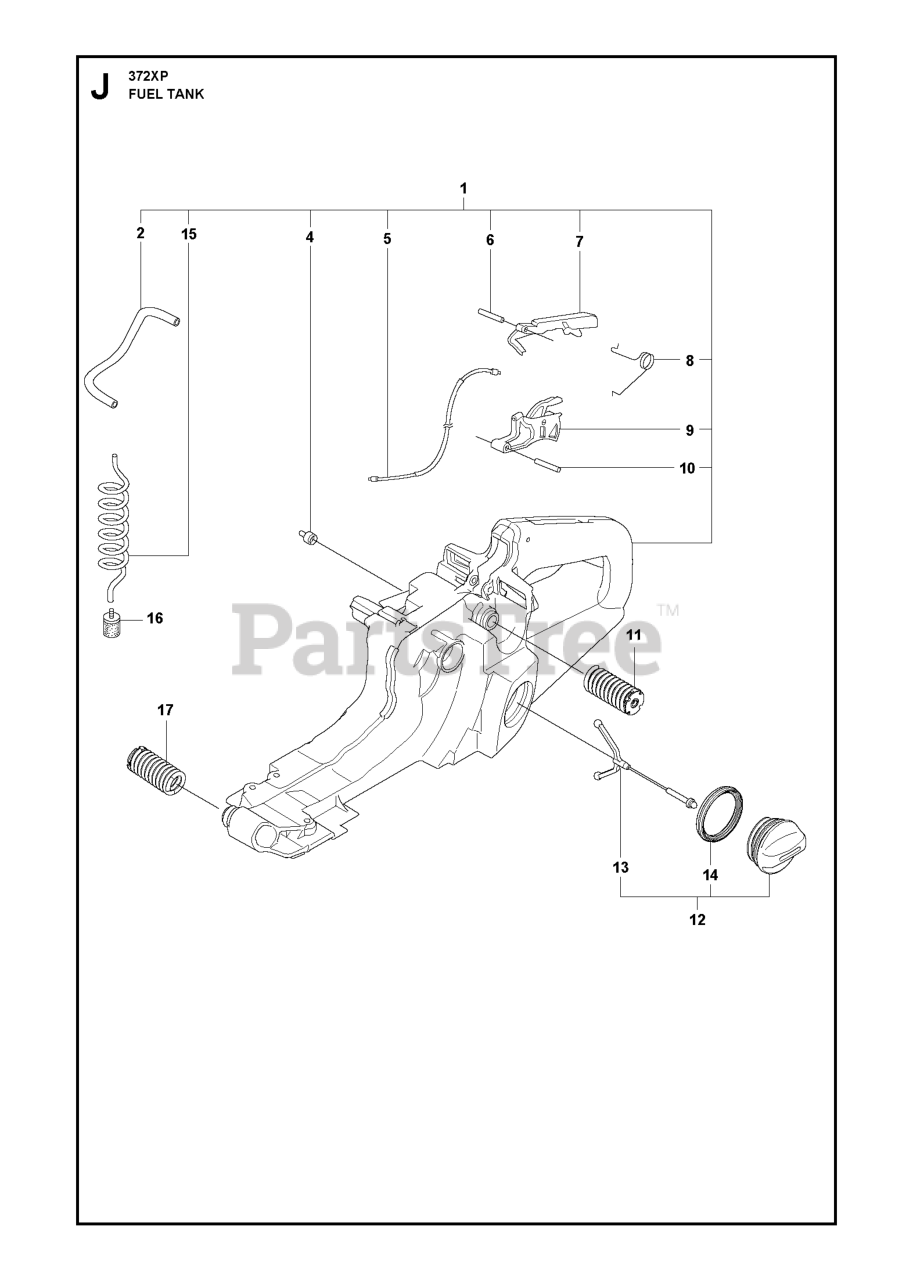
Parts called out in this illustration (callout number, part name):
2	FUEL HOSE STRAIGHT 105
3	CONNECTOR
4	FILTER PLUG
4	TANK VALVE
4	FUEL TANK VENT
6	PIN 3X25
7	THROTTLE CATCH
9	THROTTLE TRIGGER
10	PIN CPH8 4X20
11	ANTIVIBE MOUNT
15	FUEL HOSE SPIRAL 300
16	RP FUEL FILTER
17	Absorbers
